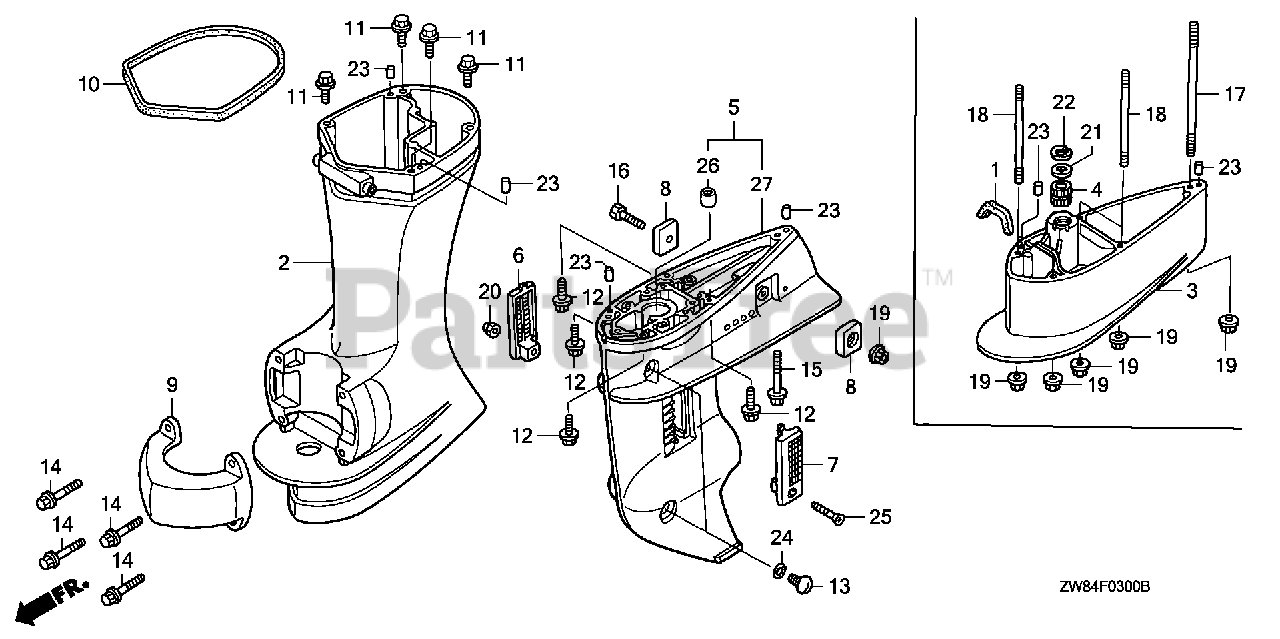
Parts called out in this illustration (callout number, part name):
1	GROMMET, WATER PUMP HOUSING
2	CASE, EXTENSION *NH282MU* (L) (OYSTER SILVER METALLIC-U)
3	SEPARATOR, EXTENSION *NH282MU* (UL) (OYSTER SILVER METALLIC-U)
4	BUSH, VERTICAL SHAFT
5	CASE, GEAR *NH282MU* (UL) (OYSTER SILVER METALLIC-U)
6	SCREEN, R. WATER
7	SCREEN, L. WATER
8	METAL, ANODE
9	HOUSING, MOUNTING (LOWER) *NH282MU* (OYSTER SILVER METALLIC-U)
10	RUBBER, COVER (LOWER)
11	BOLT, FLANGE (8X35)
13	BOLT, OIL CHECK
14	BOLT, FLANGE (6X20)
16	BOLT, HEX. (6X25)
17	BOLT, STUD (6X211)
18	BOLT, STUD (6X162)
19	NUT, SELF-LOCK (6MM)
20	NUT, SELF-LOCK (5MM)
21	WASHER (20MM)
22	CIRCLIP (INNER) (30MM)
23	PIN, DOWEL (6X10)
24	O-RING (5.5X1.5)
25	SCREW, OVAL (5X28)
26	BEARING, NEEDLE (15X21X16)
27	CASE, GEAR *NH282MU* (OYSTER SILVER METALLIC-U)
